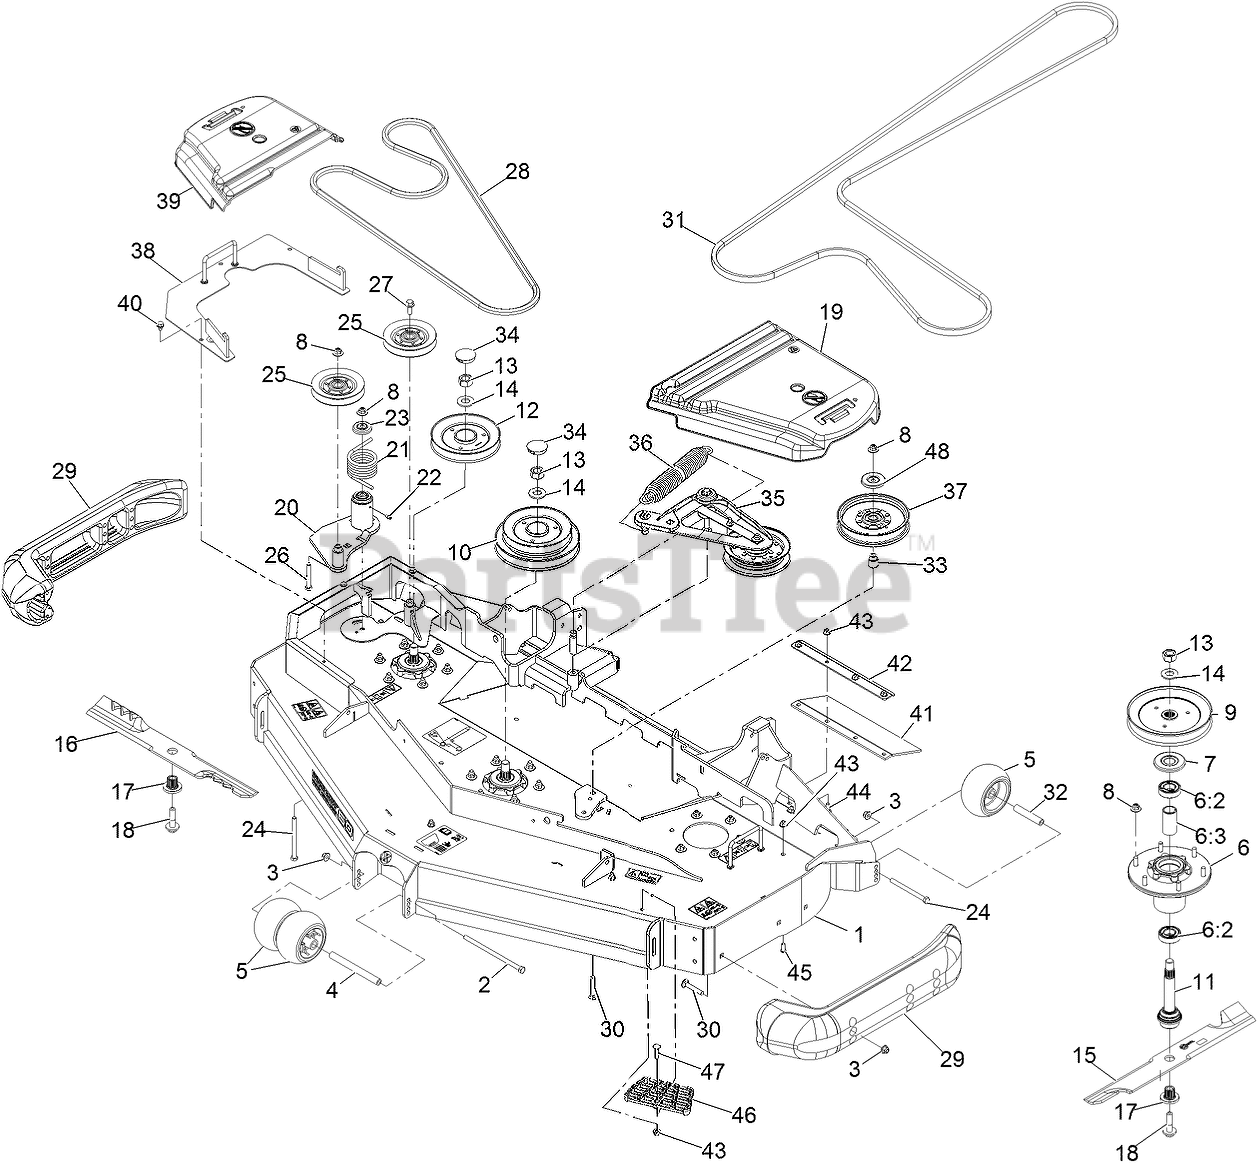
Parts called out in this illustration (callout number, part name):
1	DECK-RD60 NLZ, W/DECALS
2	SCREW-HH
3	NUT-HF, NI
4	SPACER-WHEEL
5	ROLLER-SCALP, ANTI
6	ASM-CUTTER HSG WITH BEARINGS
6:2	BEARING-BALL
6:3	SPACER-BEARING
7	GUARD,BEARING TOP .989
8	Nut-Nyloc 3/8-16 Flg
9	SHEAVE,BLADE DRIVE 7.25
10	SHEAVE, DOUBLE 60RD
11	ASM-SPINDLE AND SEAL
12	SHEAVE-RD REV DRIVE SERIE
13	NUT-HEX
15	Blade-Extreme 2, 20.50"
16	Blade-Low Lift 20.5, Rd60
16	Blade-Extreme 2-20.50, Rd60
17	BUSHING,SPLINED
18	SCREW,SEMS 1/2-20 X 2.19
19	COVER-BELT, LH
20	IDLER ASM
21	SPRING-TORSION
22	FITTING-GREASE
23	GUARD-TOP
24	SCREW-HH
26	SCREW-HH
27	SCREW-HHF
28	BELT
29	SKID-BUMPER, DECK
30	Bolt-Carriage 3/8-16 X 2 1/4
31	BELT
32	TUBE-SPANNER
33	BUSHING-IDLER
34	PLUG,BLACK NYLON 1.75
35	DECK IDLER ASM
36	SPRING-EXTENSION
37	IDLER-PULLEY, FLAT 6.00X1
38	COVER-DRIVE REVERSE
39	COVER-BELT, RH
41	GUARD-TIRE
42	SUPPORT-OUTER FLAP
43	NUT-HF, NI
44	SCREW-CARR
45	SCREW-HSBH
46	STEP-DECK
47	Bolt-Carriage 5/16-18 X 1 1/4
48	SHIELD-DUST
